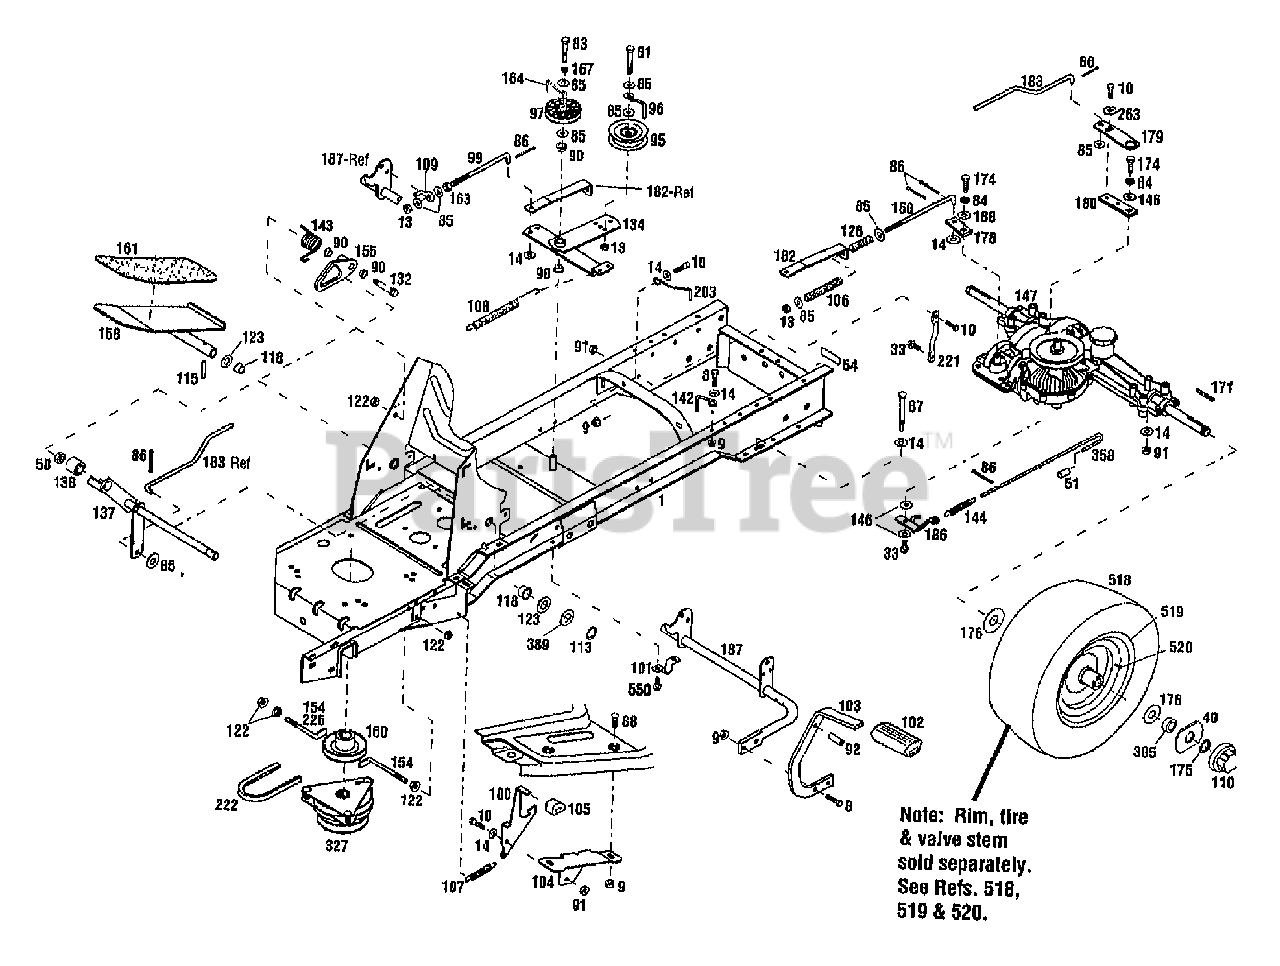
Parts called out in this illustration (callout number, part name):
1	ASSM-FRAME LTX
8	SCR-HH 5/16-18X1.0 G5 ZP
9	NUT-HFLK 5/16-18 ZP
10	SCR-HHC 5/16-18X.75 GR 5 ZP
13	NUT-LOCK 3/8-16
14	WASHER-FLAT 5/16 SAE
33	SCR-HFLK 5/16-18X.75
40	WASHER-SPEC .75X2.50
51	GRIP-HANDLE
54	DECAL-TRANS RELEASE
58	NUT-HT LK 1/4-20
81	SCR-HH 3/8-16X2.0 G5 ZP
83	SCR-HH 3/8-16X1.75 G5 ZP
84	WASHER-LK .25 ZP
85	WASHER-FLAT 3/8 SAE
86	PIN-COTTER .09X.75 ZP
87	SCR-HH 5/16-18X2.75 G5 ZP
88	SCR-CARR 5/16-18X.62 G2 ZP
90	BUSHING-.5X.5 NYLON FLNG
91	NUT-TOP/LK 5/16-18 ZP
92	PIN-.312X.75
96	GUIDE-BELT
97	PULLEY-IDLER
99	ROD-CLUTCH
100	LATCH-BRAKE CLUTCH USE1771514
101	CLIP-CLAMP .75 ID
102	PAD-FOOT PEDAL
103	PEDAL-BRAKE
104	BRKT-BRAKE LOCK
105	PAD-BRAKE
106	SPRING-COMPRESSION
107	SPRING-EXTENSION
108	SPRING-EXTENSION
109	ROD-PIVOT
110	CAP-HUB
113	RING-RETAIN .625 ID
115	PIN-ROLL .188X1.0
118	BEARING-FLANGE
122	NUT-HFLK 3/8-16 ZP
123	WASHER-1.115X.637X.06
132	SCR-SHLDR 3/8-16
134	ARM-IDLER
137	SHAFT-HYDRO PIVOT
138	BEARING-BALL
142	GUIDE-BELT
143	SPRING-TORSION
144	SPRING
146	WASHER-FLAT 5/16 SAE
147	TRANSAXLE-HYDRO
150	ROD-BRAKE
154	RETAINER-CLUTCH {13035/036}
154	RETAINER-CLUTCH {13037}
155	ARM-RETURN NEUTRAL HYDRO
158	ASSM-PEDAL HYDRO
160	PULLEY-ENGINE
161	PAD-FOOT PEDAL
163	NUT-HEX 3/8-16 ZP
164	GUIDE-BELT
167	WASHER-LK .375 @ DEPL
171	KEY-3/16X3/16X1 3/4
174	SCR-HHC 1.4-28 X .50
175	RING-RET."E".577 ID
176	WASHER-1.87X.765X.06 SPECIAL
178	BRAKE-ARM
179	ARM-CONTROL
180	ARM-HYDRO
182	BRACKET-BRAKE
183	ROD-HYDRO CTRL
186	BRACKET-DUMP VALVE
187	ASSM-BRAKE PEDAL
188	WASHER-FLAT .25 DIA
203	GUIDE-BELT
221	SUPT-TRANSAXLE
222	BELT-V
226	GUIDE-BELT {13035/036}
263	WASHER-LK .312 PYRAMIDAL
327	CLUTCH-ELECTRIC
358	ROD-DUMP VALVE
385	SPACER-1.0X.766X.413
389	WASHER-1.0X.64X.029
518	TIRE-20X8.00-10
519	WHEEL-REAR
520	STEM-VALVE
550	SCR-HFLK 5/16-18X.75
